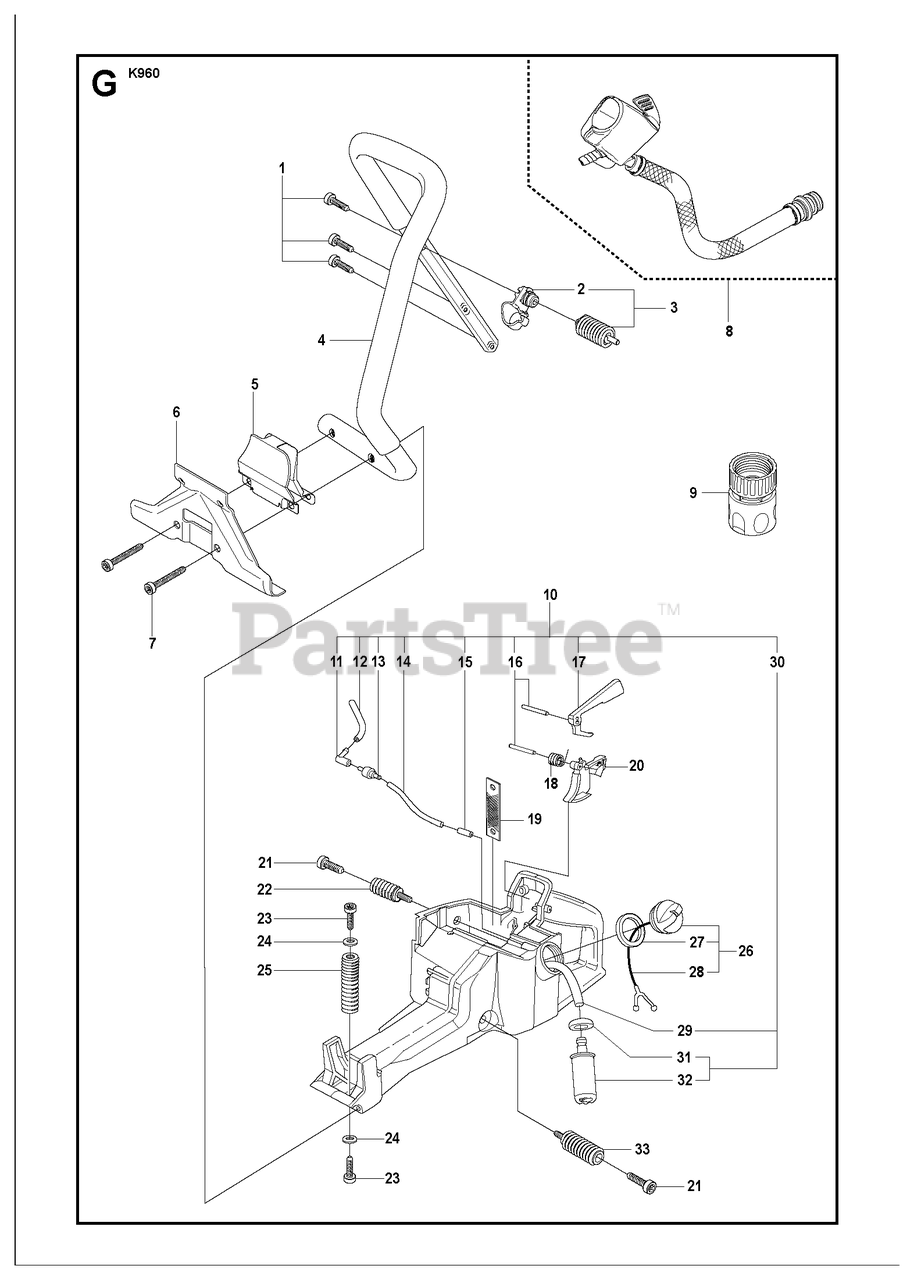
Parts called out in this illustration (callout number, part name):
1	SCREW ITXSCT
3	ANTIVIBRATION ELEMENTIncl. 2
5	PROTECTIVE PLATE
7	SCREW ITXSCT
8	HOSE ASSY
9	COUPLER
10	FUEL TANKIncl. 11 - 17, 30
11	CONNECTION BEND
12	FUEL HOSE
14	FUEL HOSE
16	PARALLEL PIN
17	THROTTLE LOCKOUT
18	SPRING THROTTLE TRIG
21	SCREW ITXSCM
22	ANTIVIBRATION ELEMENT
23	SCREW ITXSCM
25	ANTIVIBRATION ELEMENT
26	TANK CAP ASSYIncl. 27, 28
29	FUEL HOSE
30	FUEL FILTERIncl. 31, 32
